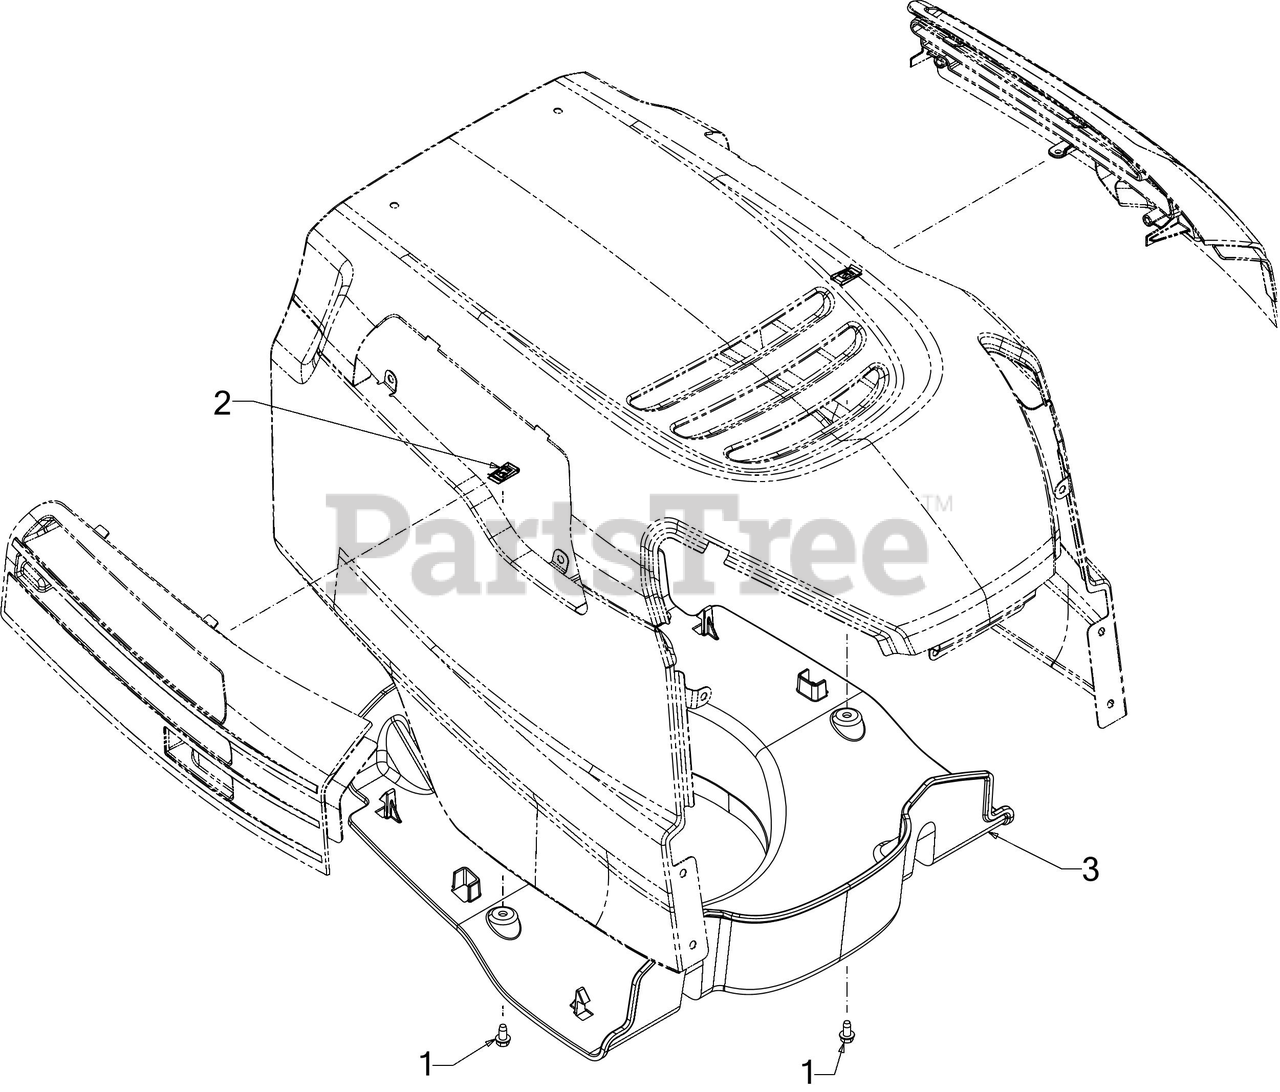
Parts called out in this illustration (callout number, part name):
1	SCREW 1/4-20 X.500
2	SPEED NUT
3	PLENUM P STYLE
